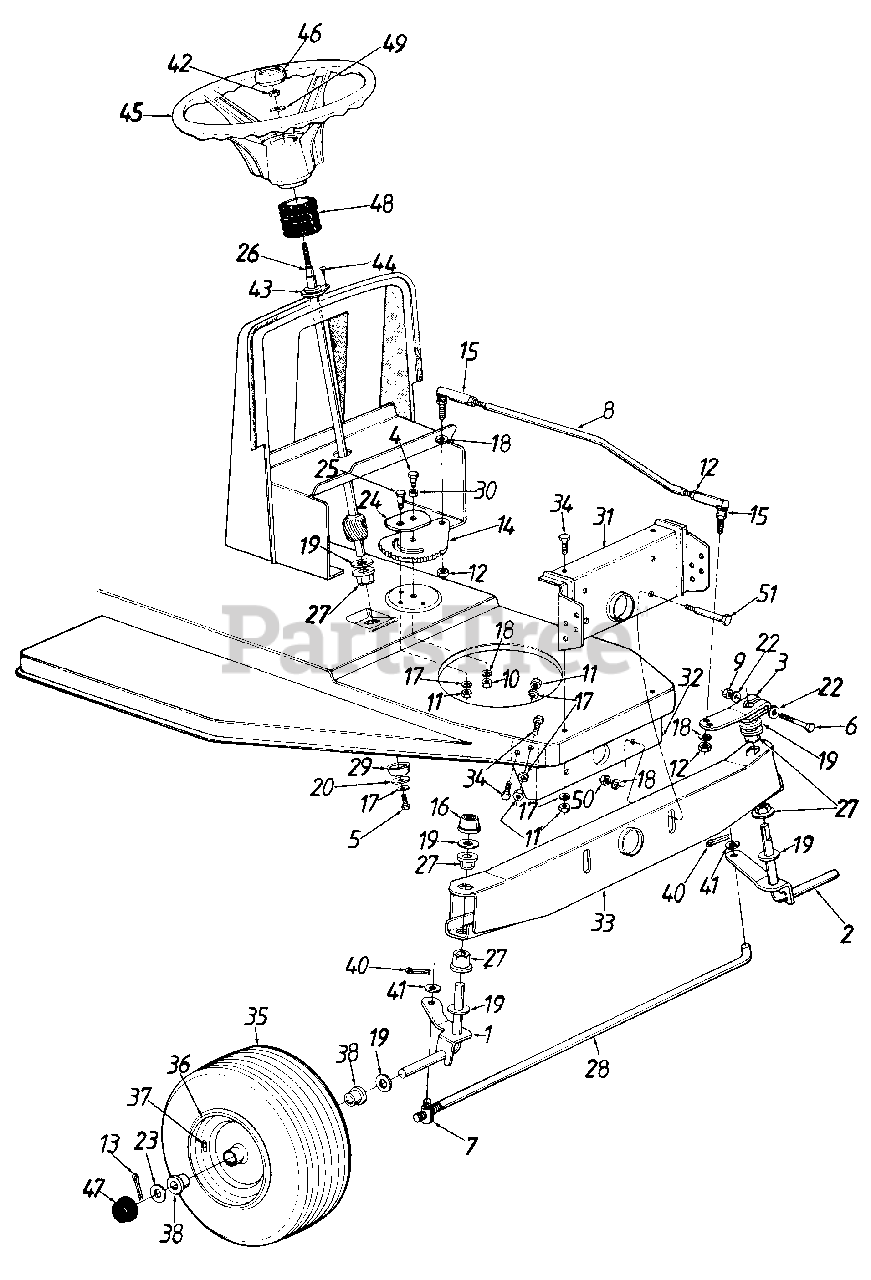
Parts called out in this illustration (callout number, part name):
1	Front Axle Ass'y. R.H.
2	Front Axle Ass'y. L.H.
3	Steering Arm
4	Hex Bolt 3/8-24 x 1" Lg.
5	Hex Bolt 5/16-18 x .62"
6	Hex Bolt 5/16-24 x 2" Lg.
7	Ferrule
8	Steering Drag Link
9	Hex L-Nut 5/16-24 Thd.
10	Hex Nut 3/8-24 Thd.
11	Hex Nut 5/16-18 Thd.
12	Hex Jam Nut: 3/8-24
13	Cotter Pin 1/8 Dia.
14	Steering Gear Segment
15	Drag Link Ball Joint 3/8-24
16	Push Cap
17	L-Wash. 5/16" I.D.
18	L-Wash. 3/8" I.D.
19	Fl-Wash. .64" I.D. x 1.24"
20	Fl-Wash. .340" I.D. x 1.125"
22	Spr. Wash. .32 I.D. x .62
23	Fl-Wash. .635 I.D. x 1.585
24	Retainer Plate
25	Shld. Bolt .437 Dia. x .350
26	Steering Shaft
27	Hex Flange Brg. .634 Dia.
28	Tie Rod 18.37 Lg.
29	Spacer .985 I.D.
30	Spacer .380 I.D.
31	Front Pivot Bar Support Brkt.
32	Rear Pivot Bar Support Brkt.
33	Pivot Bar Ass'y.
34	Hex Bolt 5/16-18 x .75" Lg.
35	Front Wheel Ass'y. Comp. 13 x 6
37	Air Valve
38	Flange Bearing .632 I.D.
40	Cotter Pin 3132" Dia.
41	Fl-Wash. .406" I.D. x .75"
42	Hex L-Nut 5/16-24 Thd.
43	Steering Column Brg.
44	Cr-Sunk Scr. #10 x 518" Lg.
45	Steering Wheel
46	Steering Wheel Cap
47	Hub Cap
48	Bellow Steering Column
49	Bell-Wash. .345 I.D. x .88
50	Hex Nut 3/8-16 Thd.
51	Shld. Bolt 1/2" Dia. x 2.32"
